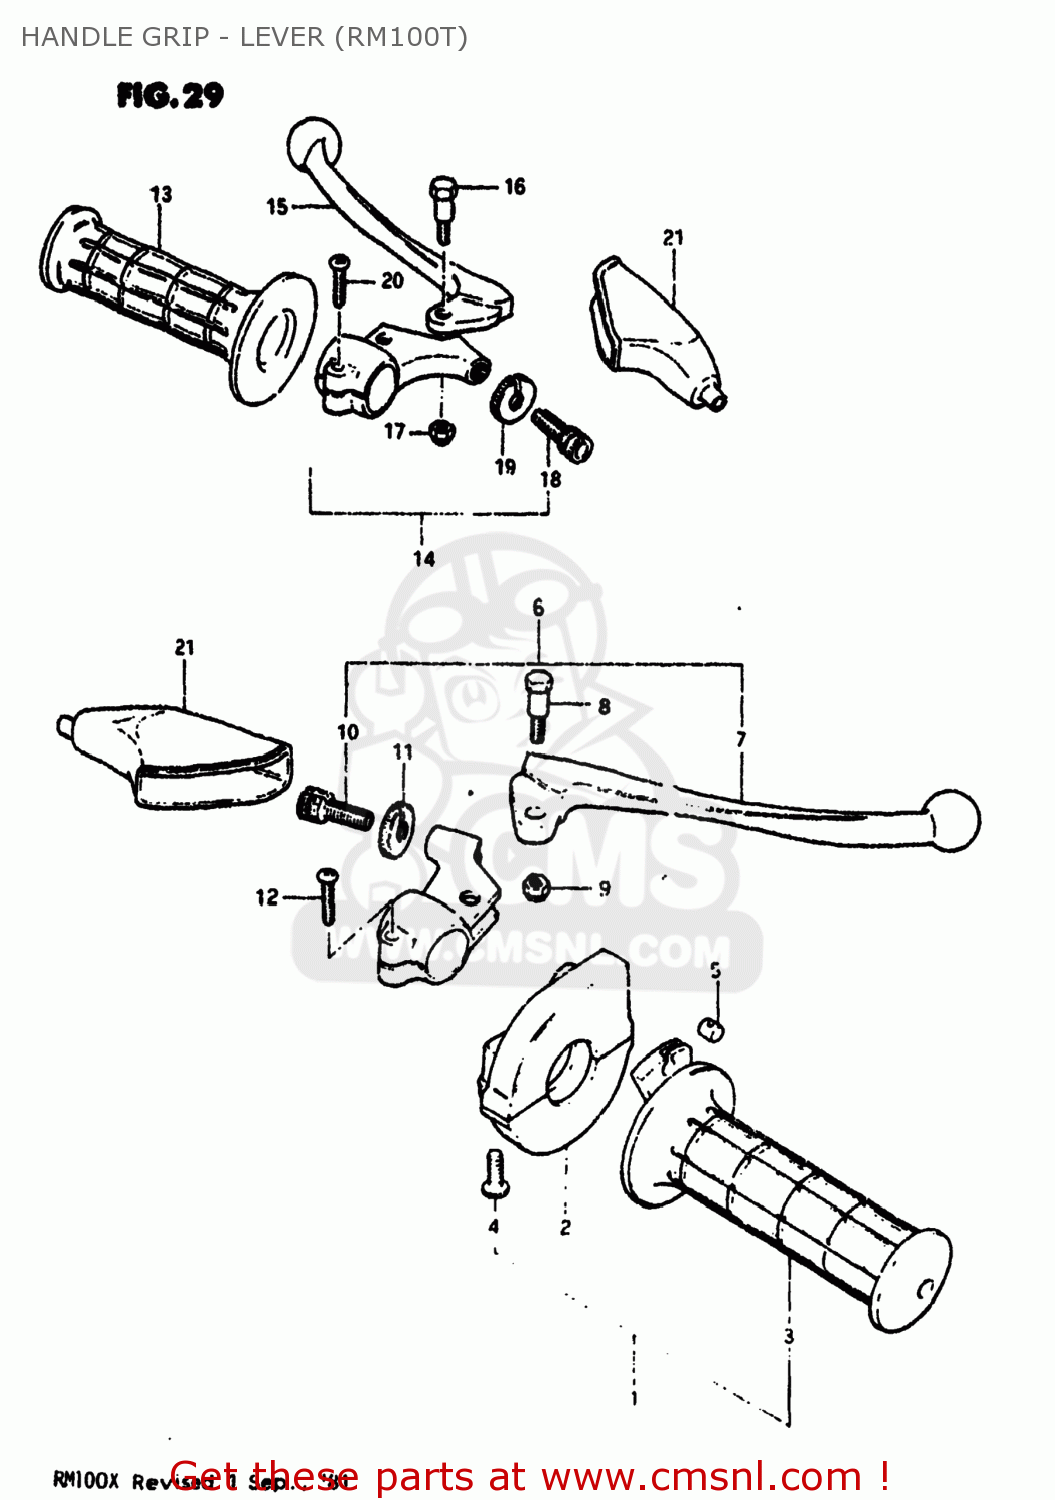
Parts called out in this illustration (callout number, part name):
1	CASE ASSEMBLY,THROTTLE
2	CASE,THROTTLE
3	GRIP,THROTTLE
4	SCREW
5	PIECE,THROTTLE END
6	LEVER ASSEMBLY,BRAKE
7	LEVER,BRAKE
8	BOLT,LEVER
9	MOER
10	ADJUSTER,CABLE
11	NUT,CABLE ADJUSTER
12	SCREW
13	GRIP,LEFT
14	LEVER ASSY,CLUTCH
15	LEVER,CLUTCH
16	BOLT,LEVER
17	NUT 6MM
18	ADJUSTER,CABLE
19	NUT,CABLE ADJUSTER
20	SCREW
21	COVER,CLUTCH LEVER
